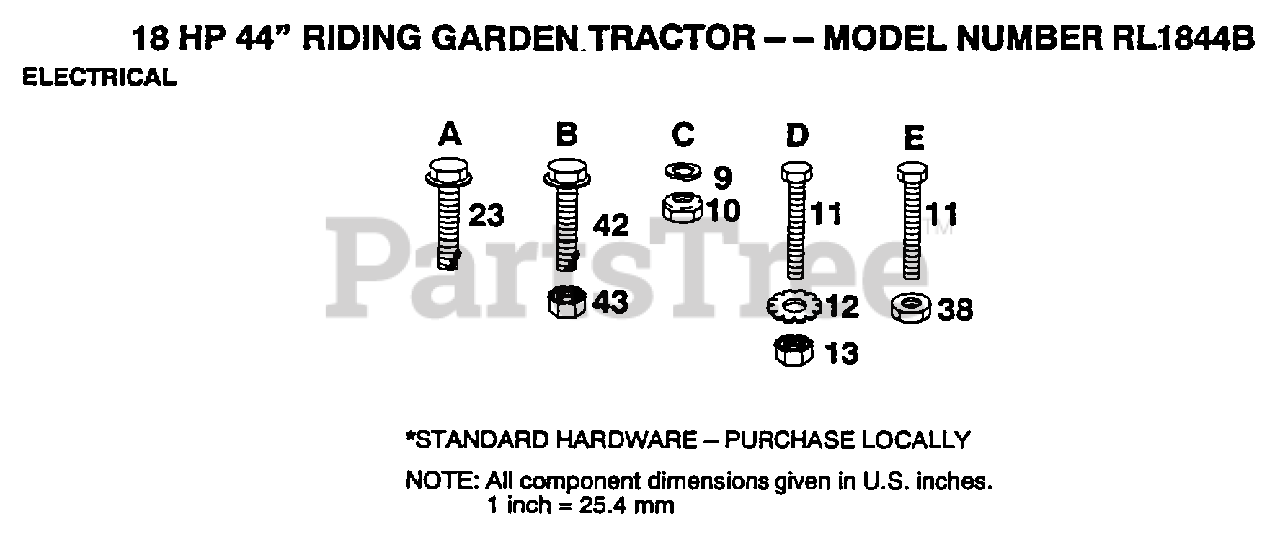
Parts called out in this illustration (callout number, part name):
10	NUT
11	BOLT
13	NUT
23	SCREW
42	SCREW
43	"NUT,KEPS"
